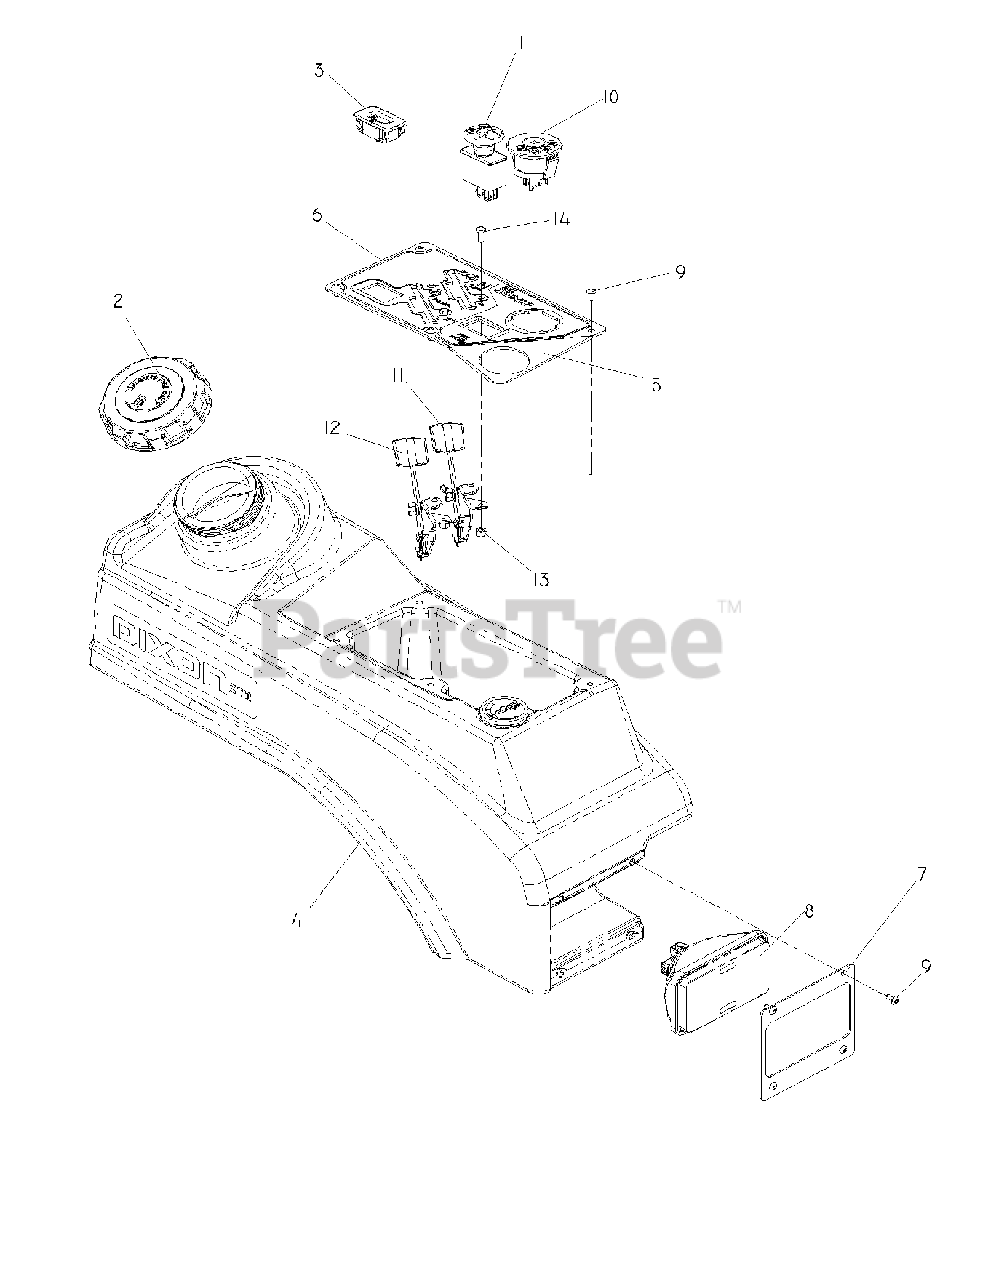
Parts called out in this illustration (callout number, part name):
1	SWITCH, BLADE
2	FUEL CAP ANTI-SPLASH
3	HOUR METER
4	TANK, FUEL, RT
5	CONTROL PANEL
6	DECAL, CONTROL
7	PLATE LIGHT
9	SCR #10-24 X 3/8 SKT HD BLK OX
10	IGNITION SWITCH
11	CABLE THROTTLE
12	CABLE THROTTLE
13	NUT 10-24 NYLOC
14	HCS #10-24 X 1/2
